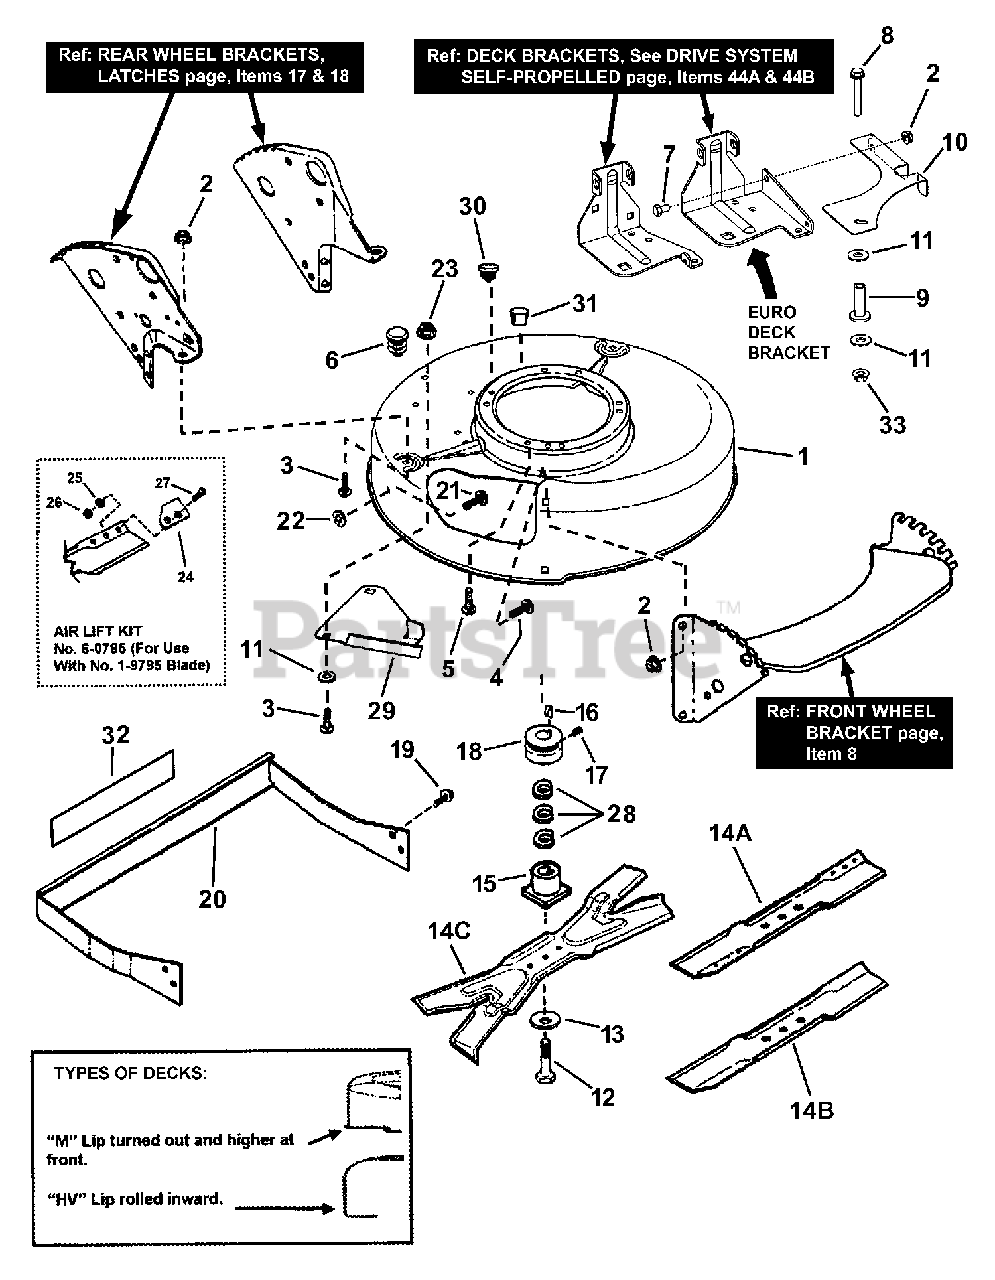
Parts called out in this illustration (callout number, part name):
1	DECK, Mower (incl. painted "HV" Deck with Decals)
1	DECK, Mower, 21" Hi-Vac (HV)
1	DECK, Mower (Includes painted "Euro M" Deck with No Decals)
1	* DECK, Mower, 21" Non-Adj Air (was 7041857 or 7057784)
2	NUT, 5/16-18 Hex Flange Lock, GR 5
3	BOLT, 5/16-18 x 1/2", Short Neck Carriage, GR 5
4	BOLT, 5/16-18 x 1-1/8" Short Neck Carriage, GR 5
5	SCREW, 3/8-16 x 1" Self-Tapping
6	PLUG, Hole, Polyethylene
7	SCREW, 5/16-18 x 1/2" Hex Head Cap, GR 5
8	BOLT, 5/16-18 x 2-1/4", Hex Flange Lock
9	BUSHING, .388 x .625 x 1.62
10	COVER, Belt
11	WASHER, 7/16" Flat
12	SCREW, 3/8-24 x 2" Hex Head Cap, GR 5
13	WASHER, Cone
14A	BLADE, Cutter, 21" Air Lift (European)
14B	BLADE, Cutter (Standard Lift)
14C	BLADE, 21" Ninja (Quad Edge)
15	HUB, Blade Drive 25mm I.D.
16	KEY, Woodruff #HP-506 Hi-Pro
17	SET SCREW, 5/16-18 x 5/16" Hex Socket
18	PULLEY, Engine (25mm I. D. x 2-1/8" O.D.)
19	SCREW, 1/4-20 x 1/2" Hex Flange Self-Tap (was 90539)
20	WELDMENT, Fender
21	BOLT, 5/16-18 x 3/4" Short Neck Carriage GR 5
22	RETAINER, 5/16" Bolt
23	NUT, 5/16-18 Hex Flange Lock, GR 5
24	AIR LIFT
25	WASHER, 5/16" Internal Tooth Lock
26	NUT, 5/16-24 Hex, GR 5
27	SCREW, 5/16-24 x 21/32" Machine
28	SPACER, .06 Thick
29	COVER, Belt
30	PLUG, 5/16" Square Hole
31	PLUG, 5/16" Round Hole
32	DECAL, Caution, International Symbols
33	NUT, 5/16-18 Hex Large Flange Center Lock
